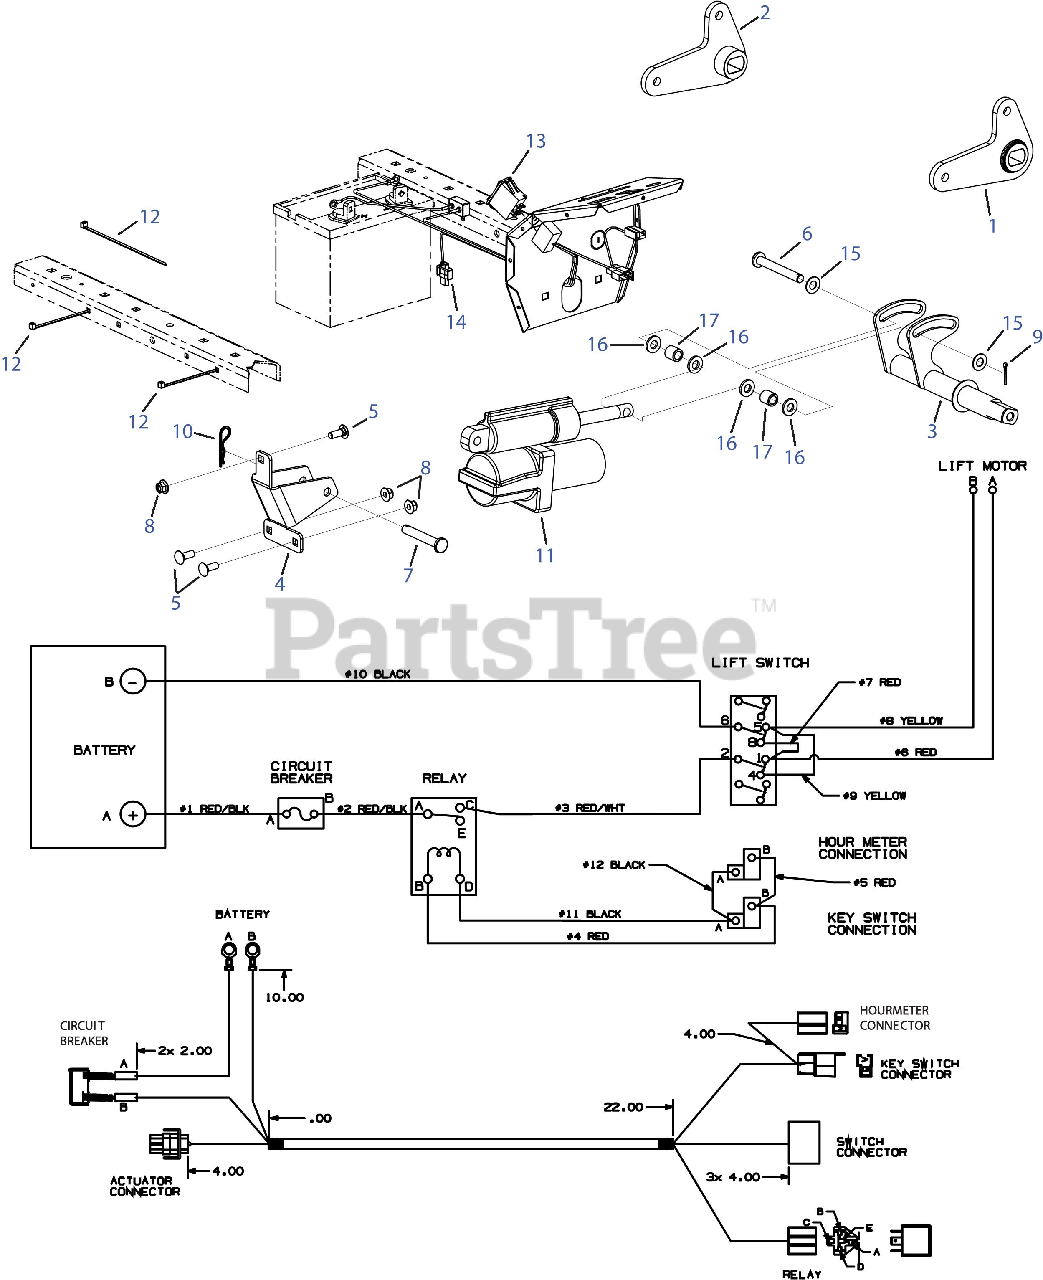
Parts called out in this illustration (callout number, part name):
1	RH Deck Lift Bell Crank
2	LH Deck Lift Bell Crank
3	Lift Bracket Shaft
4	Deck Lift Cylinder Mount
5	Carriage Bolt, 3?8-16 x 1.00
6	Clevis Pin, .500 x 3.75
7	Clevis Pin, .500 x 3.2
8	Flange Lock Nut, 3?8-16
9	Cotter Pin, 1/8 x 1.0
10	Cotter Pin, .125 x 2.5
11	Deck Lift Cylinder
12	Cable Tie, 3?16 x .05 x 7.4
13	Deck Lift Switch
14	Deck Lift Harness
14	Electrical Connector
15	Flat Washer, .510 x 1.000 x .060
16	Flt. Washer, .510 x 1.000 x .125
17	Spacer, .501 x .750 x .775
